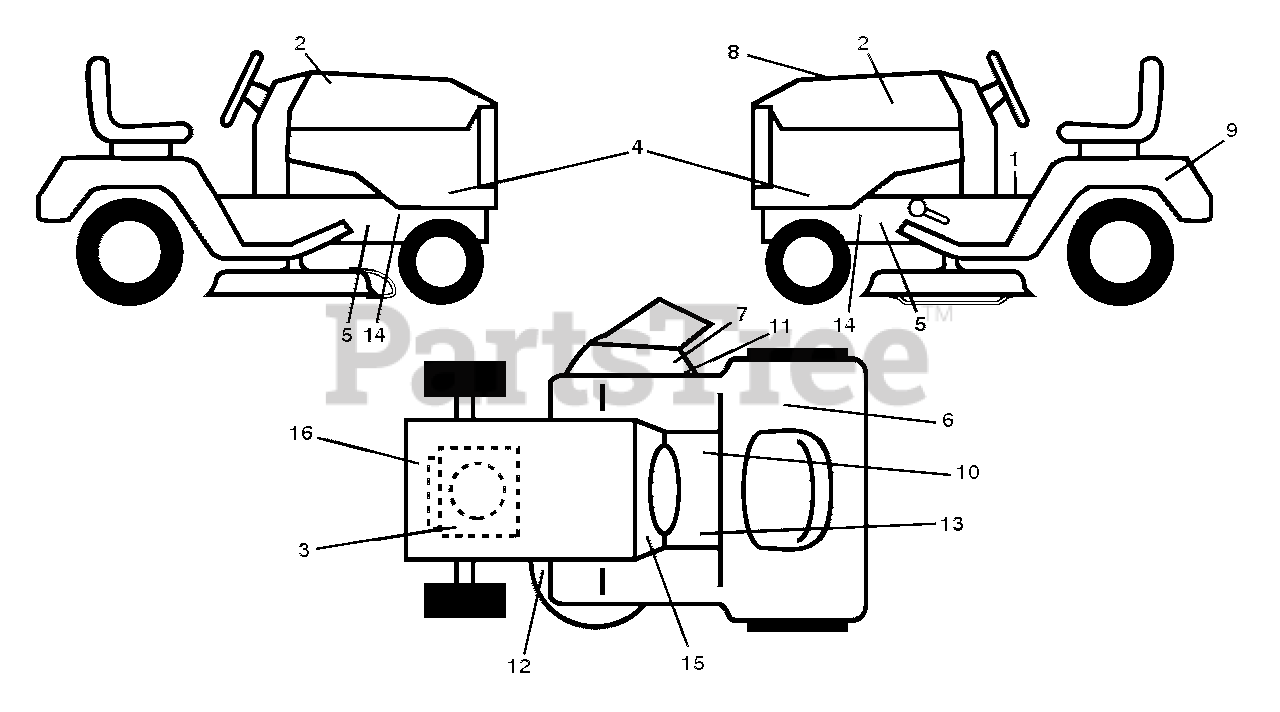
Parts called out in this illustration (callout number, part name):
1	DECAL.READ.OWN.MAN.SYMBOL.LT
2	DECAL.BADGE.170MM.TEXTLOGO.
3	DECAL.ENGINE.WARNING
5	DECAL.CHASSIS.HOT.MUFFLER
6	Decal, Certification 6MIL 100D
7	DECAL.CUTFINGER.CE.02
8	DCL.RPL.BSM31.INTK.TLW.38.PMST
9	DECAL BTRY SYMBOLS
10	DECAL.PARKING.BRAKE.SADDLE.LT
11	DECAL.DFLCTR.WARNNG.CTFNGR.SYM
12	DECAL.DECK.SCH.36,38,94.NONCR
13	DECAL.FNDR.SDLE.BRAKE.CLUTCH.6
14	DECAL.WARNING.SERVCE/FIRE
15	DECAL.SNOWFLAKE.MS498.HUSQ
16	DECAL.ENG.BS.SER4155.RS.382023
